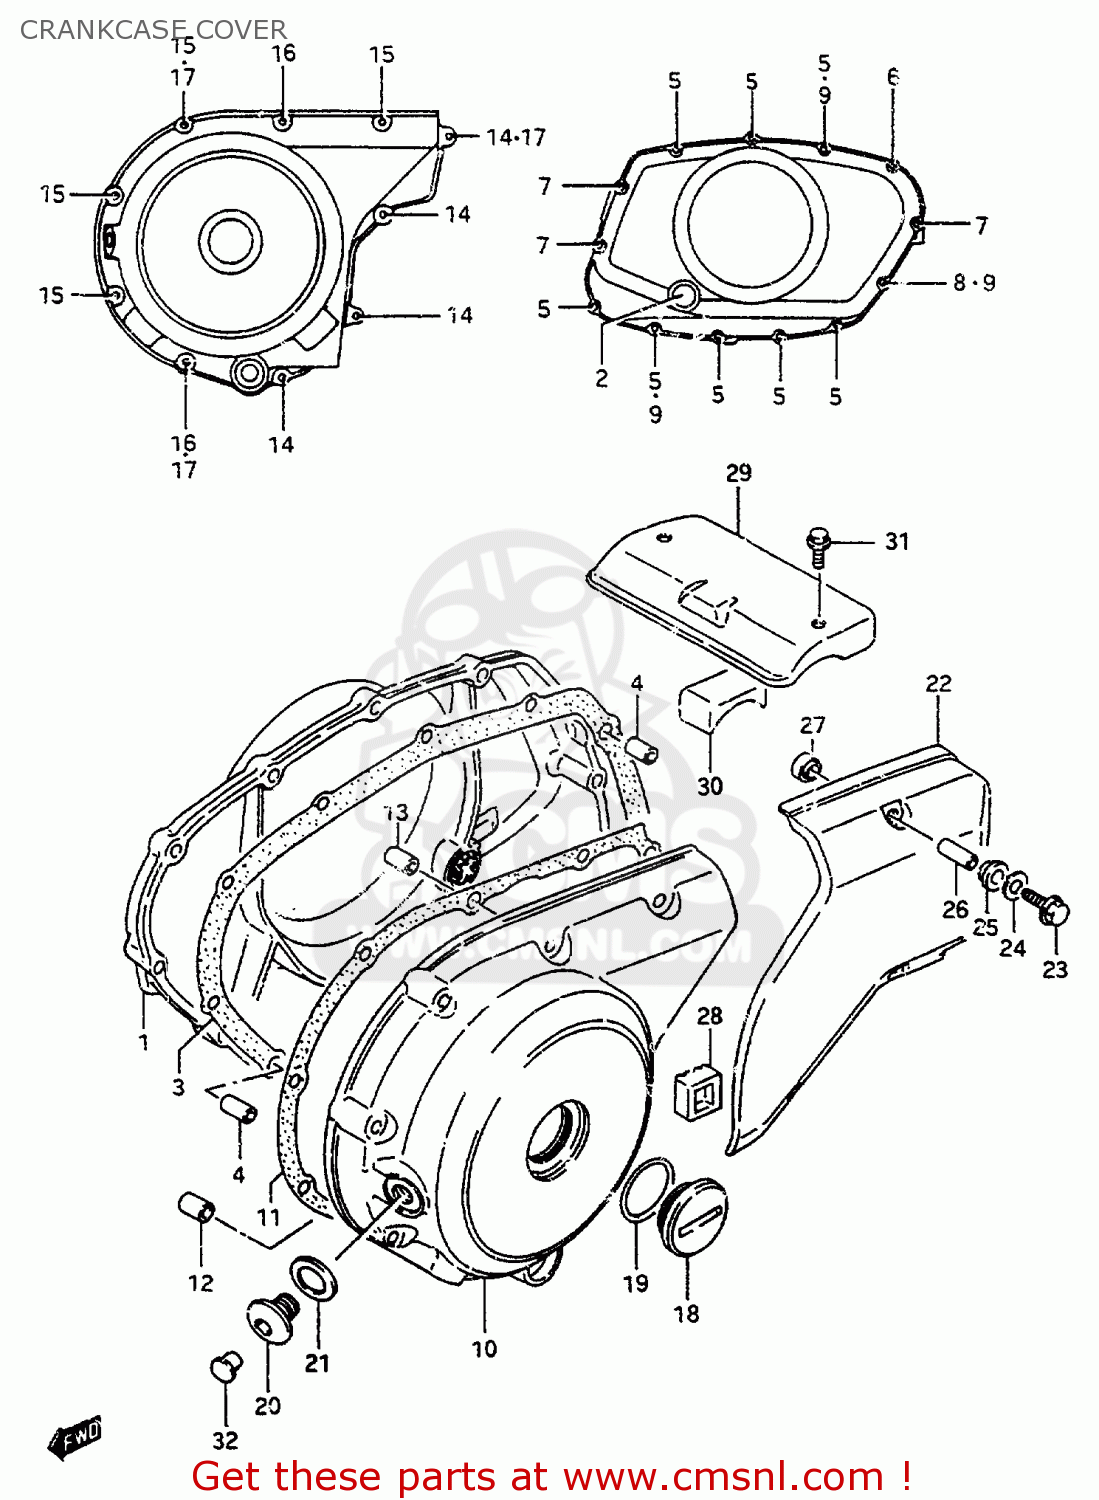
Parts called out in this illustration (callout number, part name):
1	COVER,CLUTCH
2	LENS,OIL LEVEL CHECK
3	GASKET,CLUTCH COVER (NAS)
4	PIN
5	BOLT
6	BOLT
7	BOLT
8	BOLT
9	GASKET(5.8X11X1.2) (NAS)
10	COVER,GENERATOR
11	GASKET,GENERATOR COVER (NAS)
12	PIN(8.4X11X20)
13	PIN
14	BOLT
15	BOLT
16	BOLT
17	GASKET(5.8X11X1.2) (NAS)
18	Chrome Crankshaft Plug
19	O RING(D:3.1,ID:32.7)
20	PLUG,14X12
21	GASKET(13.8X18.8X4.8) (NAS)
22	COVER,SECONDARY GEAR CASE
23	BOLT
24	WASHER
25	WASHER(8.7X15X2.1)
26	SPACER
27	WASHER(8.7X16X5)
28	DAMPER,SECONDARY COVER
29	COVER,STARTER MOTOR
30	DAMPER,MOTOR COVER
31	BOLT
32	CAP(OD:12)
